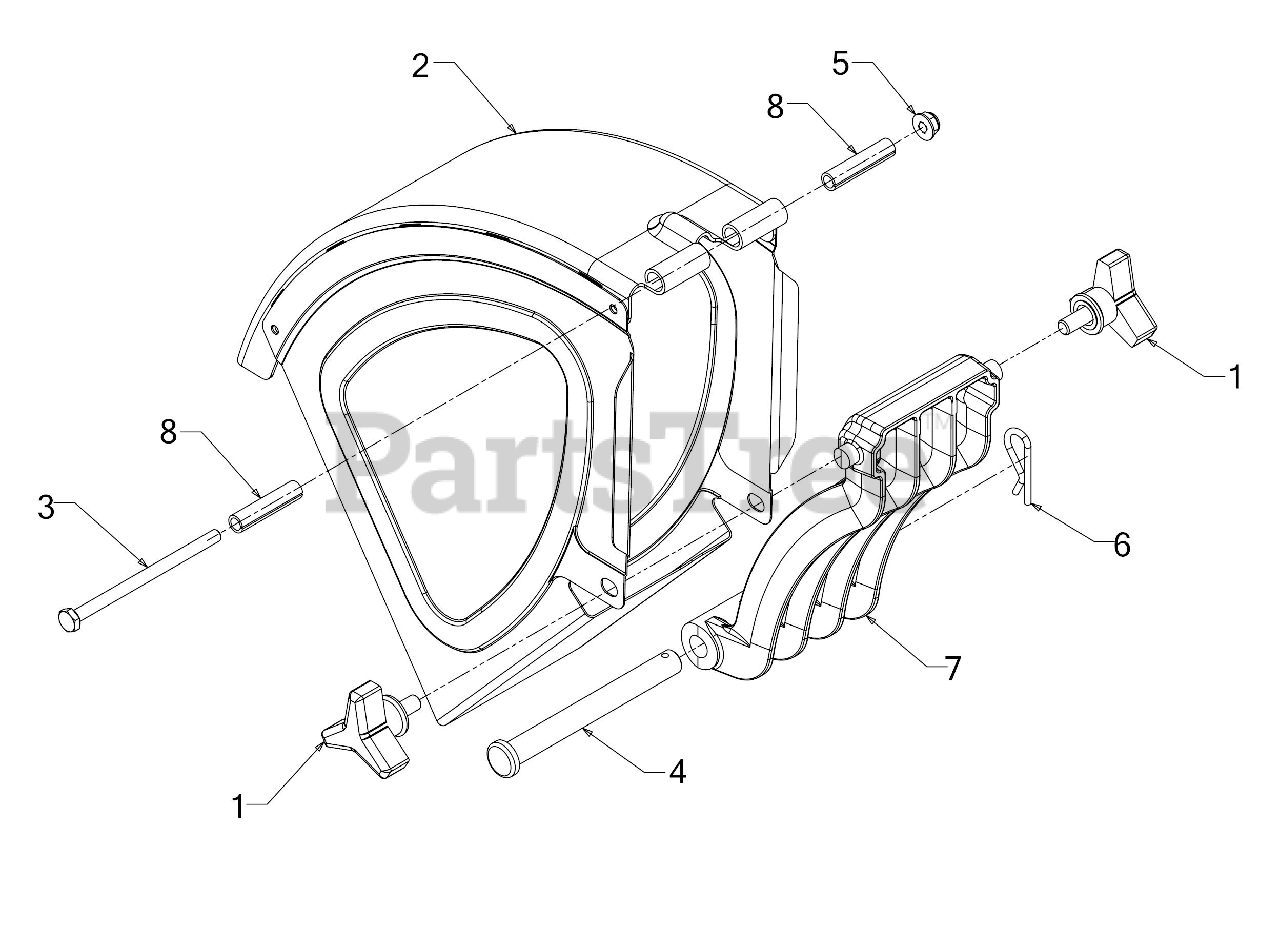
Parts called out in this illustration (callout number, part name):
1	THREE ARM KNOB
2	DISCHARGE CHUTE ASSEMBLY
3	SCREW 1/4-20 x 4 GR2
4	CLEVIS PIN
5	FLANGE LOCK NUT
6	COTTER PIN
7	SHREDDER SCREEN
8	SPACER-.260 x .3
